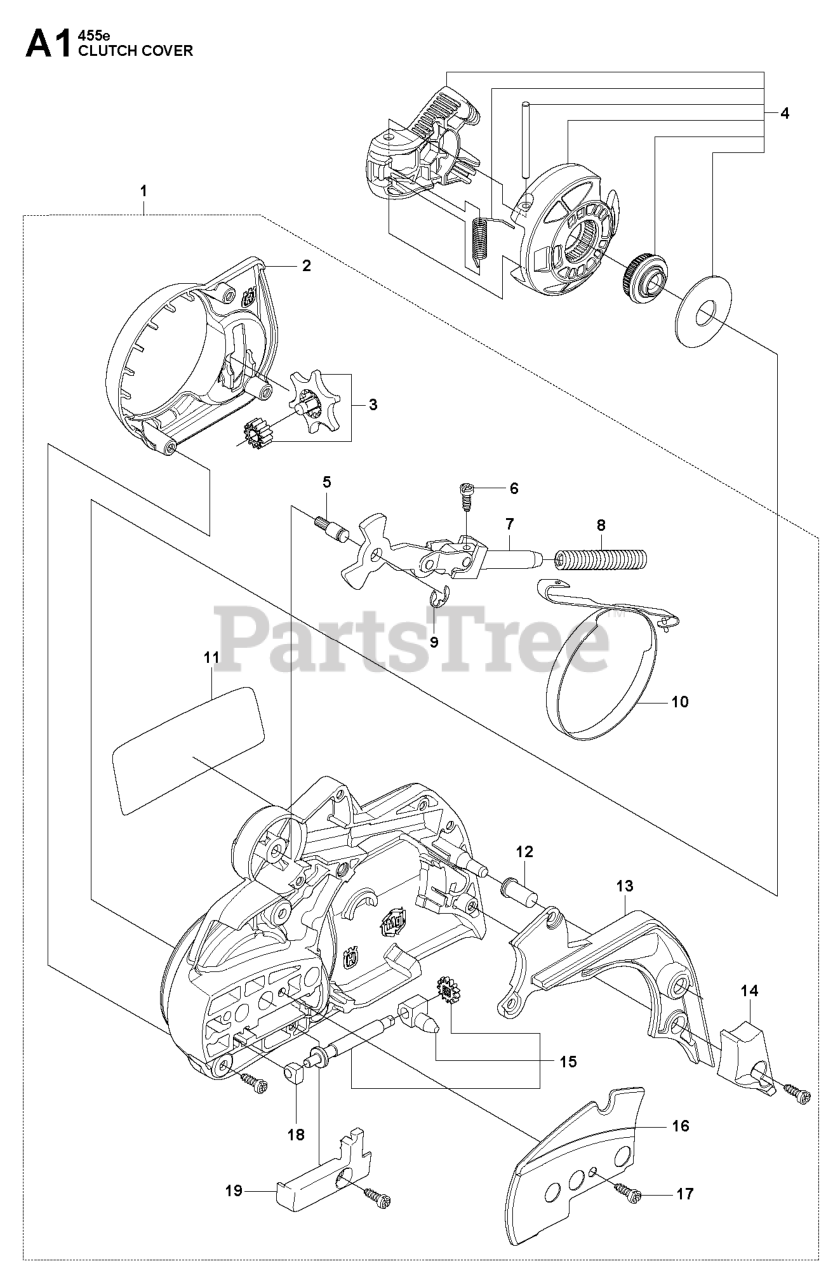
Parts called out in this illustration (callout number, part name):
1	CLUTCH HOUSING COMPLETE
2	HEAT SHIELD
3	CHAIN TENSIONER WHEEL, COMP.
4	KNOB, COMPLETE
10	BRAKE BAND
11	DECAL, CLUTCH HOUSING
13	COVER, CHAIN BRAKE
14	WEAR GUARD, CHAIN
15	CHAIN TENSIONER SCREW, COMP.
18	BEARING SLEEVE
